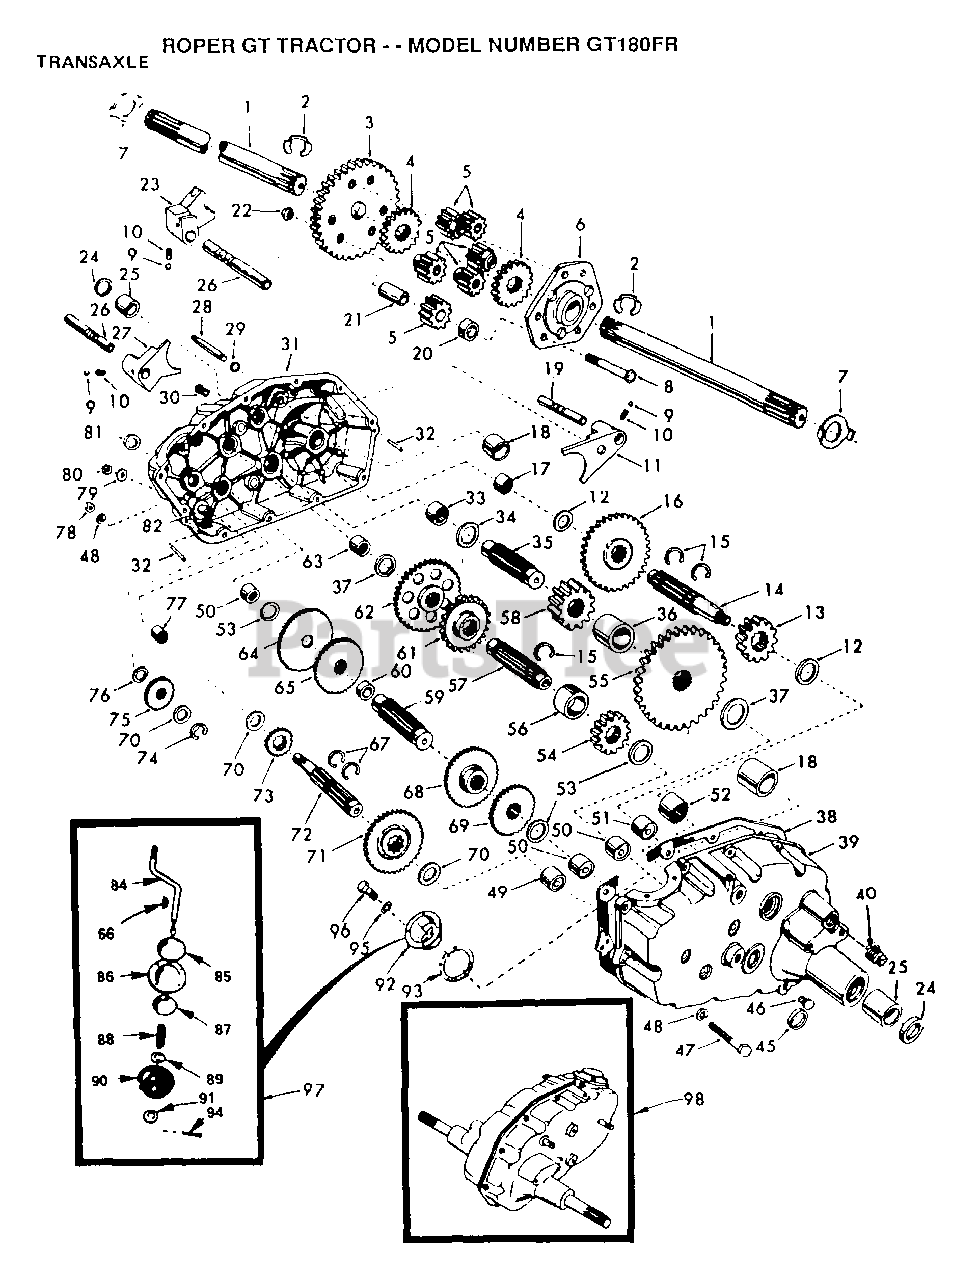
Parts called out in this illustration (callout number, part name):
1	SHAFT.AXLE.T
3	FINAL GEAR T
4	DIFF GEAR T
5	DIFF PINION T
6	DIFF CARRIER T
8	BOLT
11	SHIFT FORK T
12	WASHER .T
13	RED PINION T
14	GEAR SHAFT T
15	SNAP RING T
16	GEAR T
17	"T, BEARING"
18	BEARING
19	SHAFT
20	SPACER T
21	PINION RS
22	GRIPCO NUT
23	SHIFT FORK T
24	OIL SEAL STD
25	BRNG. T
27	FORK T
28	SHIFT SHAFT
30	VALVE M
31	GEARCASE RH
32	PIN T
33	NEEDLE BRNG T
34	RACE T
35	GEAR SHAFT T
37	RACE T
38	GASKET
39	GEARCASE LH
40	PLUG PIPE
45	SEAL T
47	HEX BOLT
49	"TI, BEARING"
50	NEEDLE BRNG T
51	NEEDLE BRNG T
52	"STD, BEARING"
53	BRNG RACE
54	RED PINION T
55	RED GEAR T
56	PINION SPACER T
57	GEAR SHAFT T
58	FINAL PINION T
59	GEAR SHAFT T
60	SPACER T
61	RED PINION T
62	RED GEAR T
63	RACE T
64	LOW SPEED GEA T
65	REVERSE GEAR T
66	KEY T
67	RING STD
68	INTERMED GEAR T
70	"T, BEARING"
71	CLUSTER GEAR T
72	INPUT SHAFT T
73	LO SPEED PINION T
75	IDLER GEAR T
76	WASHER T
77	BRNG T
78	NUT.HEX.5/16-18
79	WASHER T
80	NUT
81	SEAL STD
84	GEAR SHIFT LVR T
85	CAP T
86	COVER AND PIN T
87	GUIDE BALL T
88	SPRING TI
89	WASHER
90	SEAL T
91	WASHER
92	GEAR SHIFT GA T
93	GASKET T
94	COTTER PIN
95	LOCKWASHER
96	BOLT
97	GEAR SHFT LVR T
